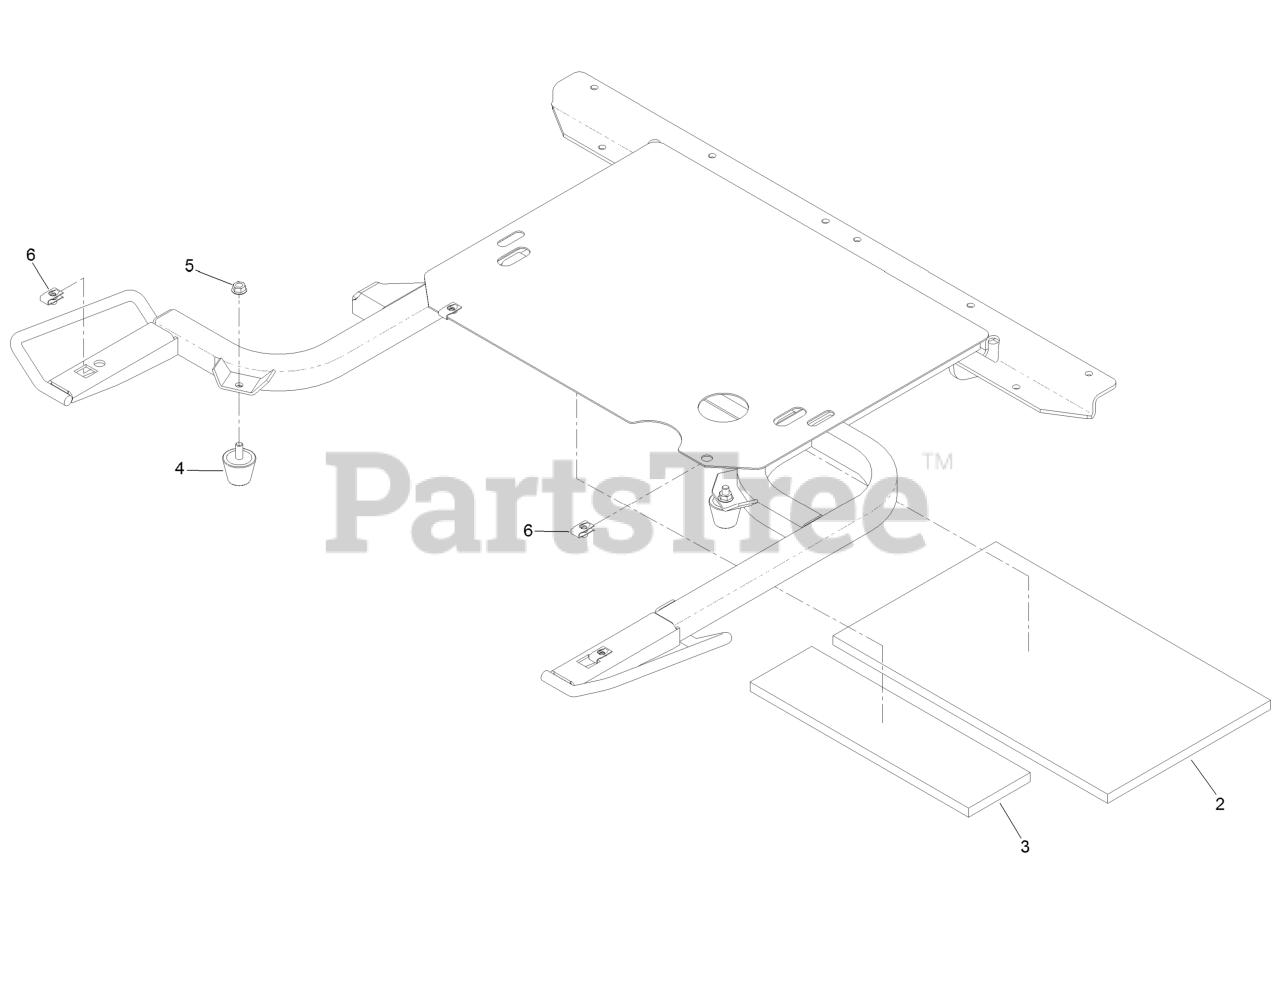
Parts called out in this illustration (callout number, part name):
2	Insulation-Foam Pad, Rear
3	Insulation-Foam Pad, Front
4	Bumper-Rubber
